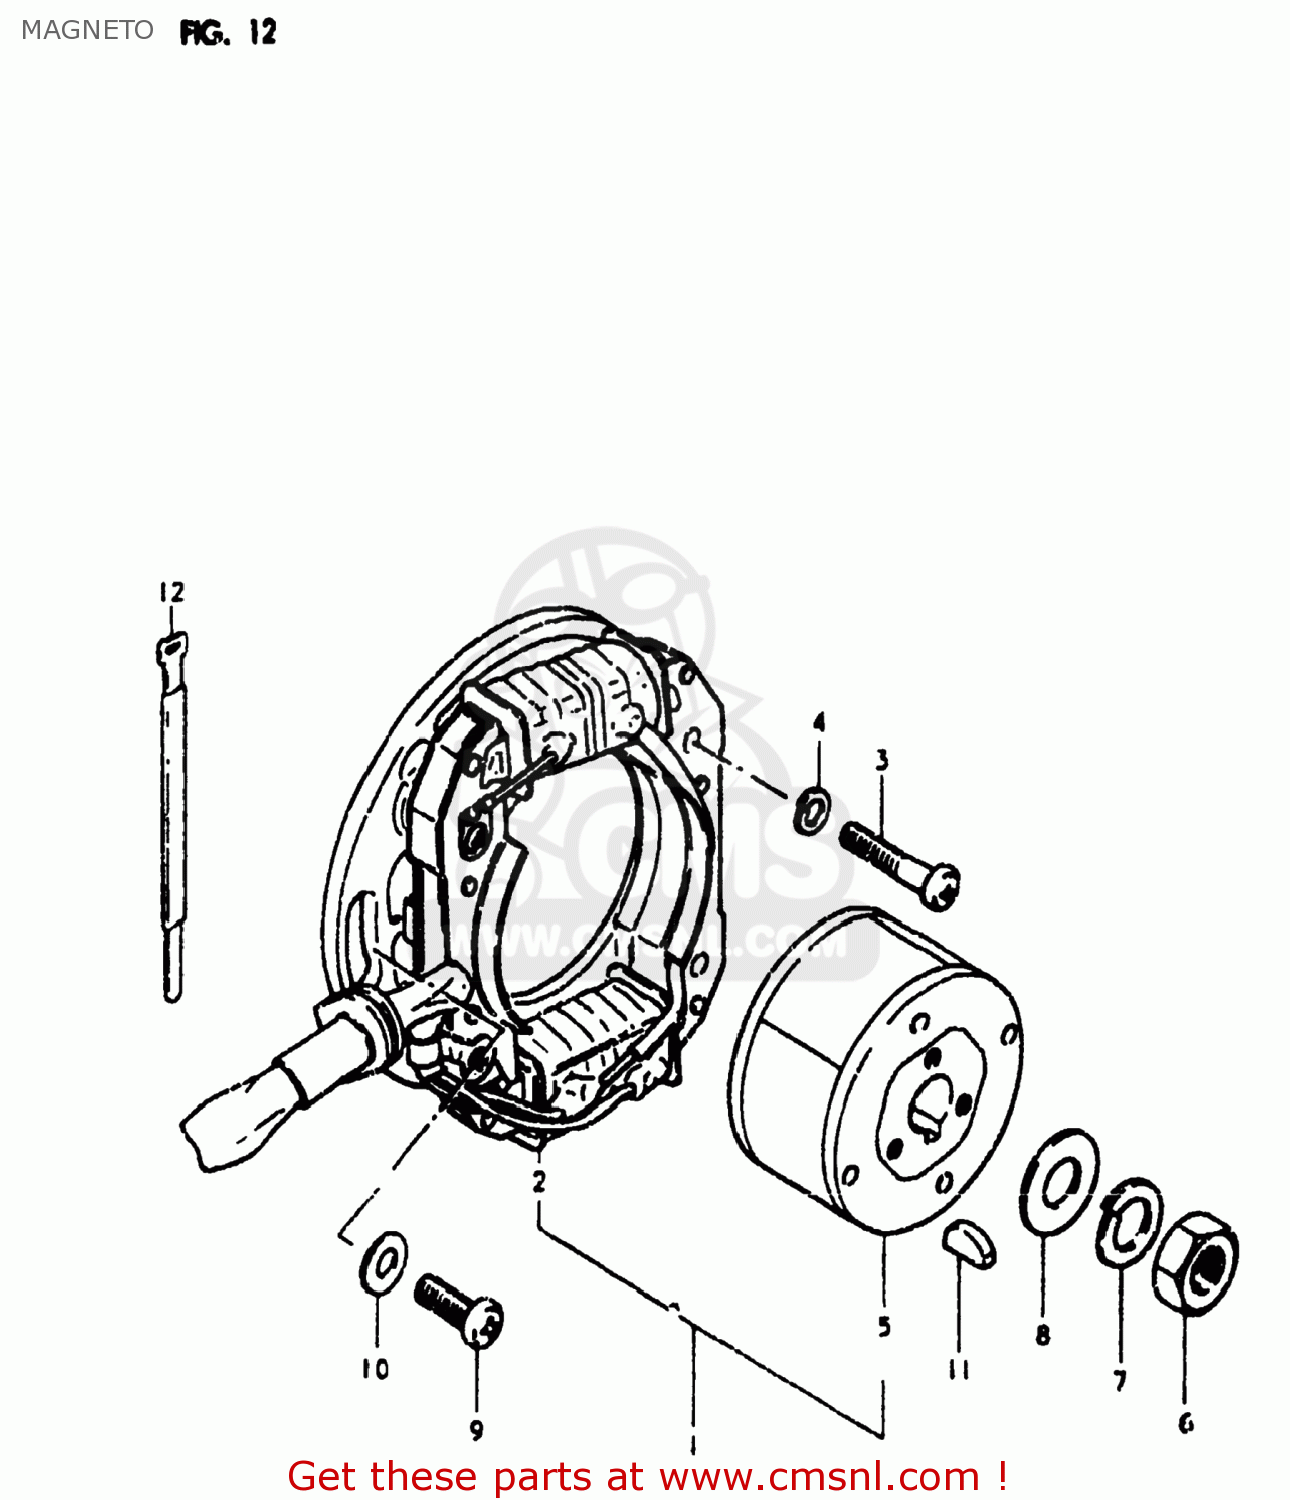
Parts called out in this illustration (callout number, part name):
1	MAGNETO ASSEMBLY
2	STATOR ASSEMBLY
3	SCREW 5X20
4	LOCK WASHER
5	ROTOR ASSEMBLY
6	NUT (10MM)
7	LOCK WASHER
8	WASHER
9	SCREW
10	WASHER
11	KEY 4MM
12	CLAMP
